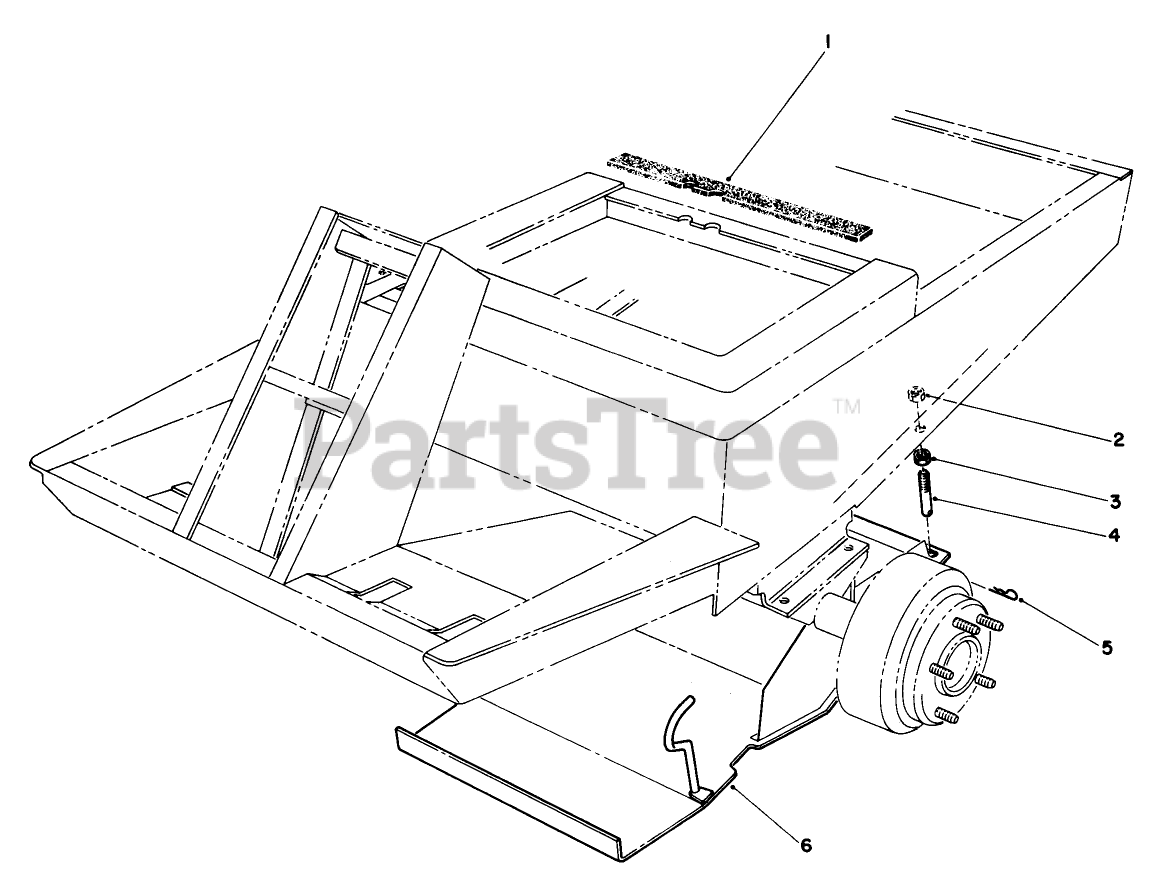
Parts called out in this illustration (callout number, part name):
1	Seal-Foam
2	NUT-HH
3	NUT-JAM
4	PIN MOUNTING
5	PIN-COTTER
6	Assembly-Shield
